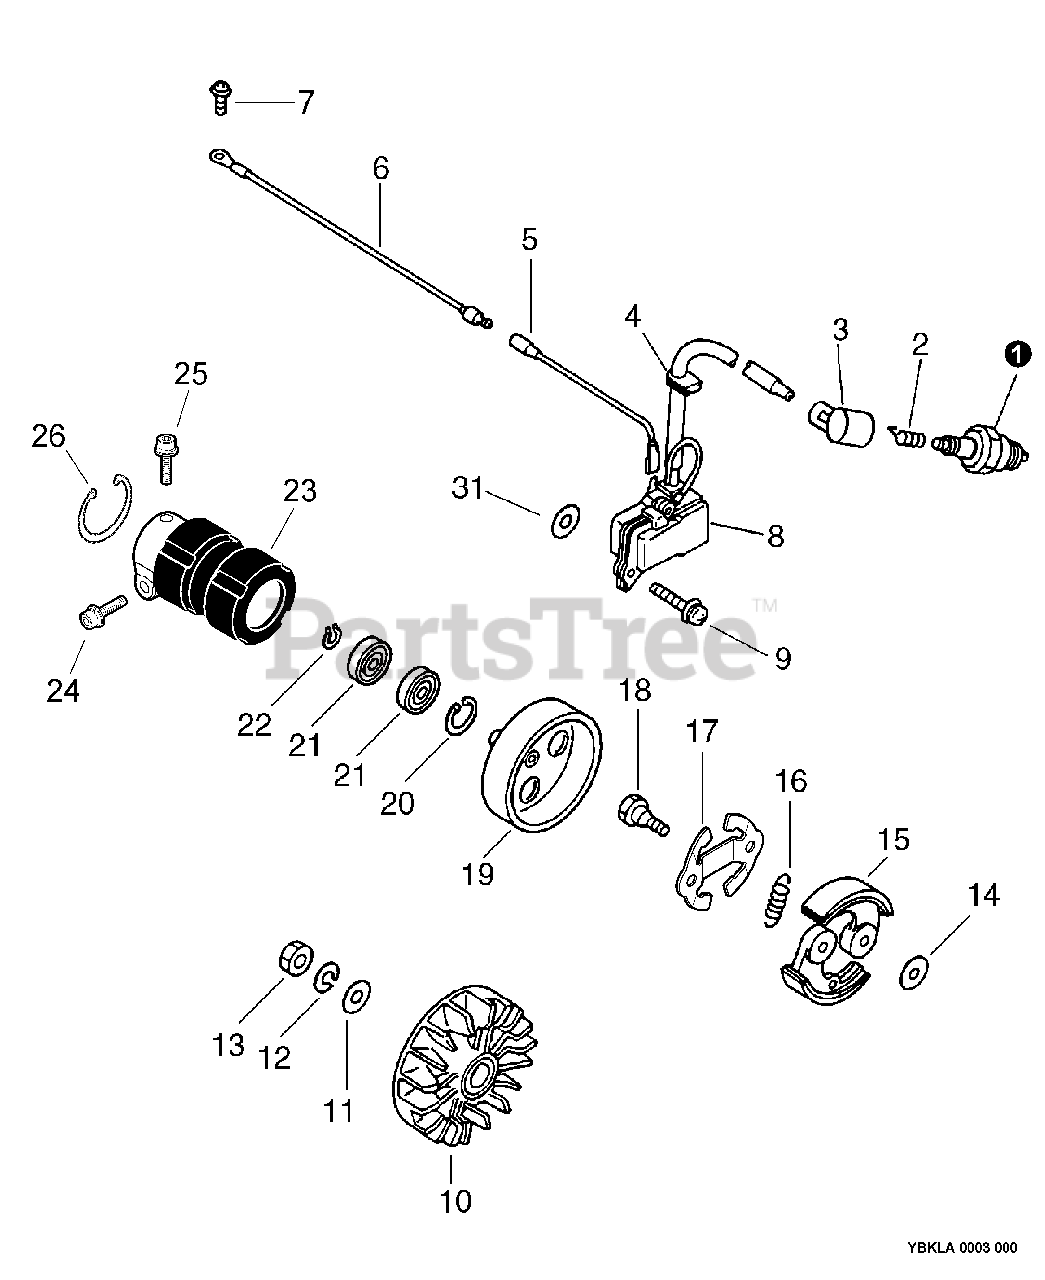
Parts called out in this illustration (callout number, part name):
1	SPARK PLUG - BPM7A
2	TERMINAL, SPARK PLUG
3	CAP, SPARK PLUG
6	LEAD - GROUND
7	SCREW 5×10
8	COIL, IGNITION
9	SCREW 5×20
10	FLYWHEEL
11	WASHER 10.5×18×1.6
12	WASHER, SPRING 10
13	NUT 10×1.25
14	WASHER 8.2×17×1.6
15	SHOE, CLUTCH
16	SPRING, CLUTCH
17	SPRING, FLAT
18	BOLT, CLUTCH
19	DRUM, CLUTCH
20	RING, SNAP 28
21	BEARING, BALL 6001
22	RING, RETAINING - 12
23	CUSHION
24	BOLT 5×28
25	BOLT 5×12
26	RING, RETAINING Ø45
31	WASHER 6.5×11.5×0.8
